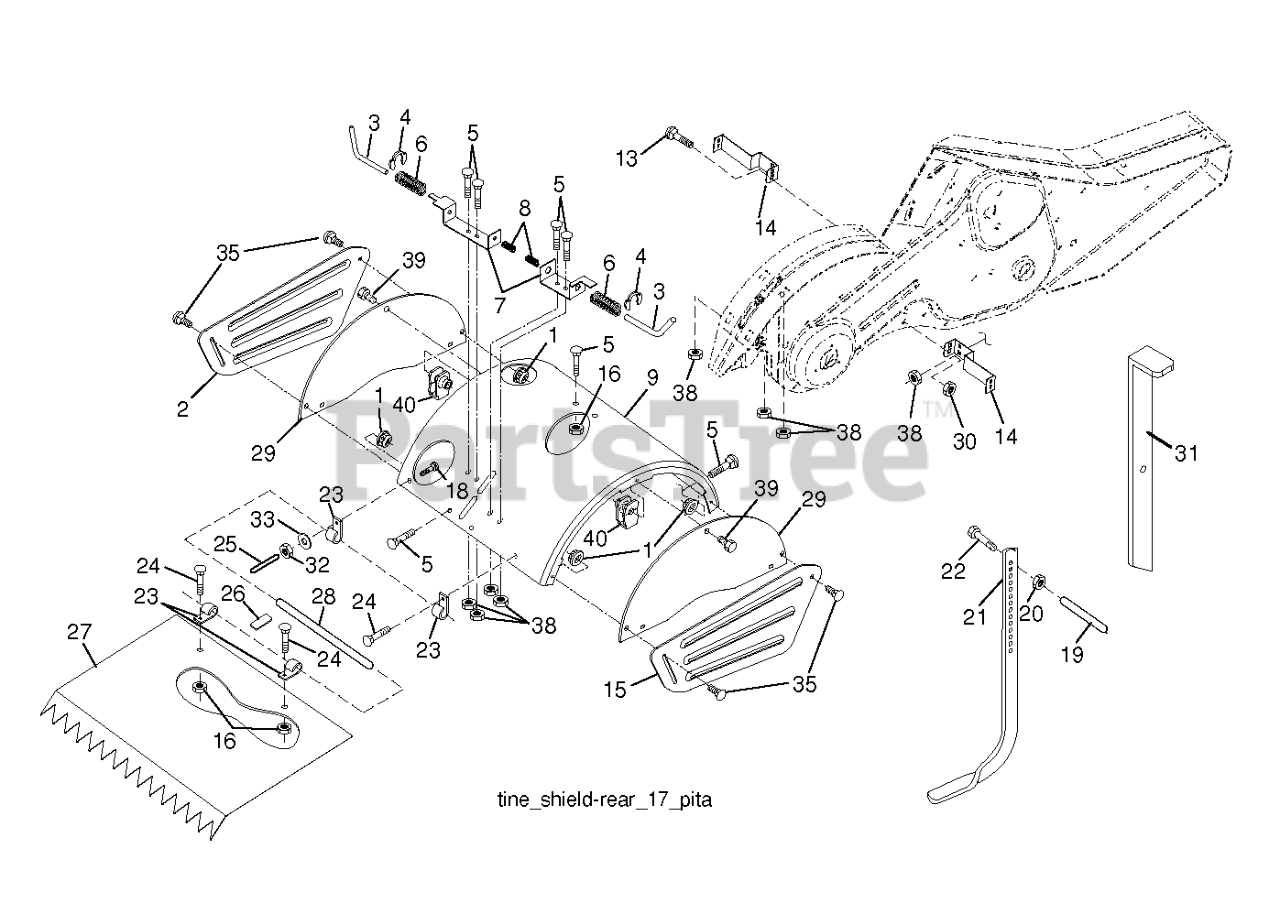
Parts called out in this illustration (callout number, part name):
1	NUT.FLANGE.5/16
2	SHIELD.PNT.SIDE.OUTER.LH.ORANG
3	STAKE PIN TI
4	RING, KLIP
5	BOLT, RDHD SQNK 5/16-18 X 3/4
7	BRACKET
8	SPRING CRT
9	SHIELD.TINE.DRT17.TILLER.ORANG
13	BOLT.CARRIAGE.5/16-18
14	BRACKET.TINE.SHIELD.BLACK
15	SHIELD.SIDE OUTER.RH.ORANGE
16	NUT T
20	NUT.HEX.3/8-16UNC
21	REPL BY 532 10 21-56
22	BOLT.375-16
24	BOLT
25	VINYL CAP TI
26	PAD IDLER TI
27	SHIELD.LEVELING.17".ORANGE
28	PIN.HINGE.TILLER
29	SHIELD.TINE.SIDE.ORANGE
30	LOCKNUT-FLANGE 5/16-18
31	STAKE.DEPTH.DRAG.BLACK.TILLER
32	NUT
33	LOCKWASHER
35	BOLT.CARR.5/16-18X5/8.SHORT
38	NUT
39	BOLT.HEX.HD.WASHER.5/16-18X.75
40	NUT.SPEED.5/16-18
